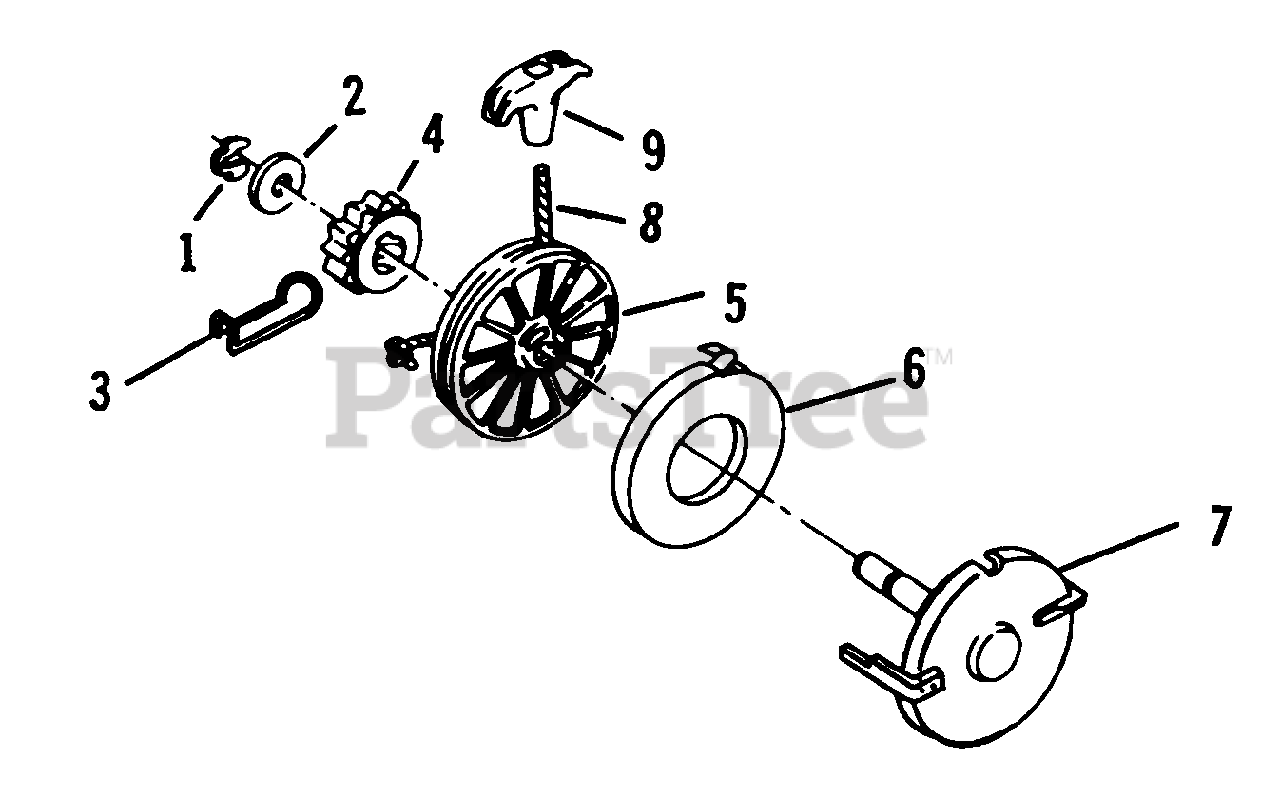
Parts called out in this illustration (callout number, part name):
1	Retainer
2	Washer
3	Spring-Drag
4	Pinion
5	Pulley
6	Spring and Retainer Assembly
7	Cup and Pin Assembly
8	Rope
9	Handle-Starter
